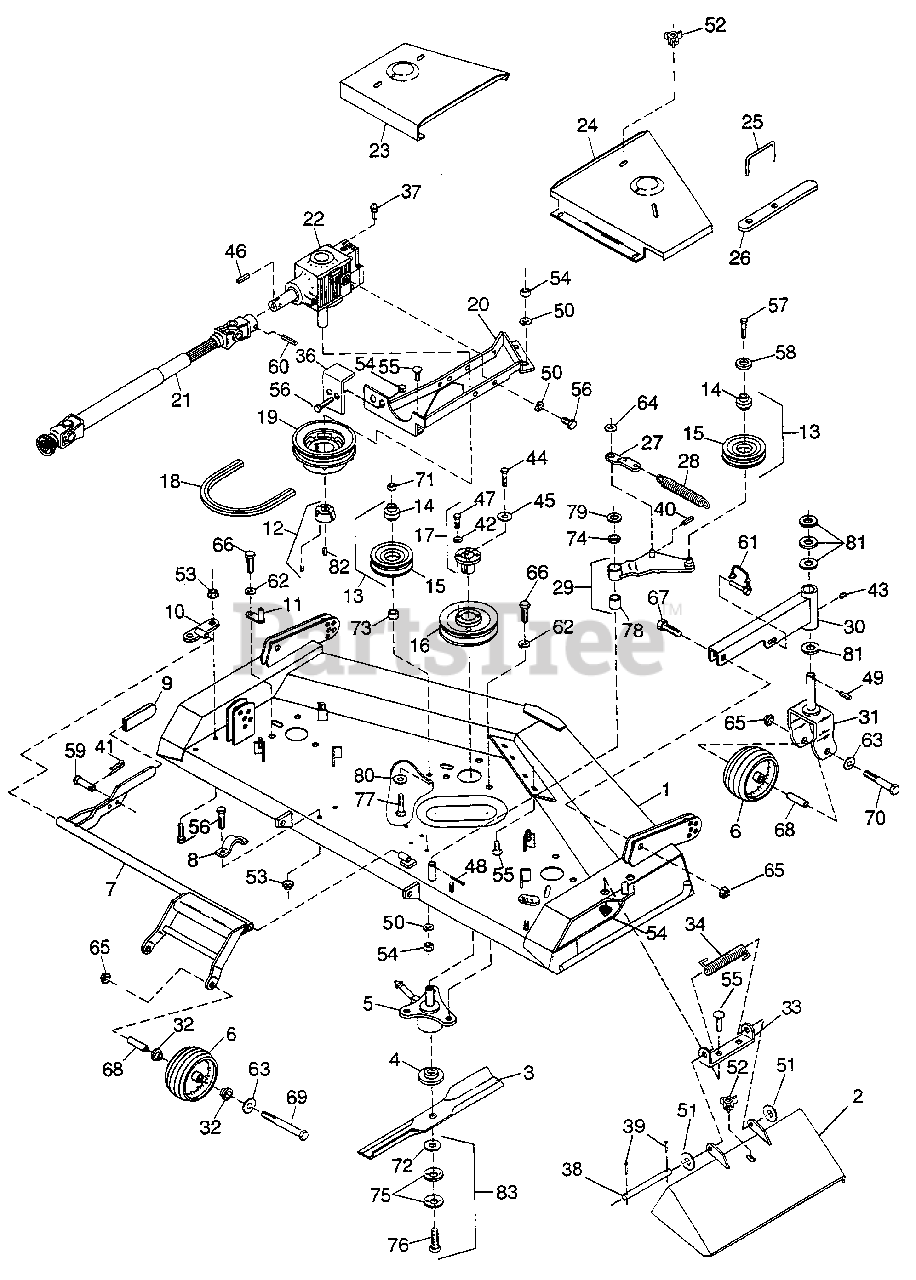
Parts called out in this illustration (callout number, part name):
1	Frame
2	Discharge chute assembly
3	CW 20-3/4 Flat high-suction blade kit w/Hdwe
4	5/8 ID x 3 x 7/16 Shoulder washer
5	CW Blade spindle assembly
6	6.25 x 3.25 x .75 Bore steel wheel
7	Rear gauge wheel shaft asy
8	1.38 Diameter clamp
9	.165 x .97 x 3.5 Grip
10	Gauge wheel shaft anchor asy
11	Belt guide assembly
12	Taper lock bushing, .81 bore
13	V-Groove idler with bearing
14	.626 ID x 1.85 OD Ball bearing
15	4.50 OD V-Groove idler
16	1 BK, 4.6 H Sheave
17	H3/4 Bushing with key and hardware
18	V-Belt WW 113 w/Aramid
19	Offset sheave, 6.65 1B 1210
20	Gearbox mounting asy, Right
21	Driveshaft assembly complete, 17.5"
21	Driveshaft assembly complete, 22"
22	Finned 1:1 bevel gearbox
23	Left belt shield
24	Right belt shield
25	Spindle lock wrench
26	Spindle wrench handle
27	Moving spring support
28	.2 x 1.45 x 8.1 Extension spring
29	Idler arm assembly, 7.75"
30	Caster arm assembly
31	Wheel yoke assembly, 6" wheel
32	.75 x 1.385 Flanged wheel bearing with groove
33	Deck bracket
34	Torsion spring, .207 x .94 x 4.86
36	Lift stop, .25 x 2.5 x 4.69
36	Lift stop, .38 x 2.5 x 3.75
36	Lift stop, 7.5
37	Plastic gearbox vent plug
38	3/8 x 7-1/4 Pin, 6-chain
39	3/16 x 1 Cotter pin
40	3/16 x 3/4 Spirol pin
41	1/8 Safety pin
42	1/4 Standard lockwasher
43	1/4-28 Taper thread grease fitting
44	1/4 NC x 3/4 Hex head cap screw GR5
45	1/4 x 7/8 x 7 GA Washer
46	1/4 x 1/4 x 7/8 Key
47	1/4 NC x 1 Hex head cap screw GR5
48	1/4 x 1-1/2 Cotter pin
49	1/4 x 1-1/2 Spring pin
50	3/8 Standard lockwasher
51	3/8 Standard flat washer
52	3/8 NC 3-Prong knob
53	3/8 NC Flanged hex locknut
54	3/8 NC Hex nut, plated
55	3/8 NC x 1 Carriage bolt GR5
56	3/8 NC x 1 Hex head cap screw GR5
57	3/8 NF x 1 Hex head cap screw GR5
58	3/8 x 1 x 7 GA Washer
59	3/8 x 1-1/4 Clevis pin
60	Spirol pin 3/8 x 1-1/2
61	Lynch pin 3/8 x 2-1/4
62	1/2 Extra-heavy lockwasher
63	1/2 Standard flat washer
64	1/2 SAE Flat washer
65	1/2 NC Flanged hex locknut
66	1/2 NF x 1 Hex head cap screw GR5
67	1/2 NC x 2-1/4 Hex head cap screw GR5
68	1/2 x 3/4 x 3-3/8 Sleeve
69	1/2 NC x 4-1/2 Hex head cap screw GR5
70	1/2 NC x 5 Hex head cap screw GR5
71	5/8 NC Hex locknut
72	5/8 Standard flat washer
73	5/8 x 1 x 9/16 HT Sleeve
74	5/8 x 1 x 1/4 Felt seal
75	5/8 x 1-3/4 x 14 GA Cup washer
76	5/8 NC x 2 Nylok hex head cap screw GR5
77	5/8 NC x 2-1/2 Carriage bolt
78	3/4 ID x 1 OD x 1-1/2 Bronze bushing
79	3/4 x 1-1/2 x 18 GA Shim washer
80	7/8 Standard SAE flat washer
81	1-1/16 x 1-9/16 x 10 GA Washer
82	Woodruff key, 3/16 x 3/4
83	5/8 NC x 2 Right hand blade bolt and washer kit
